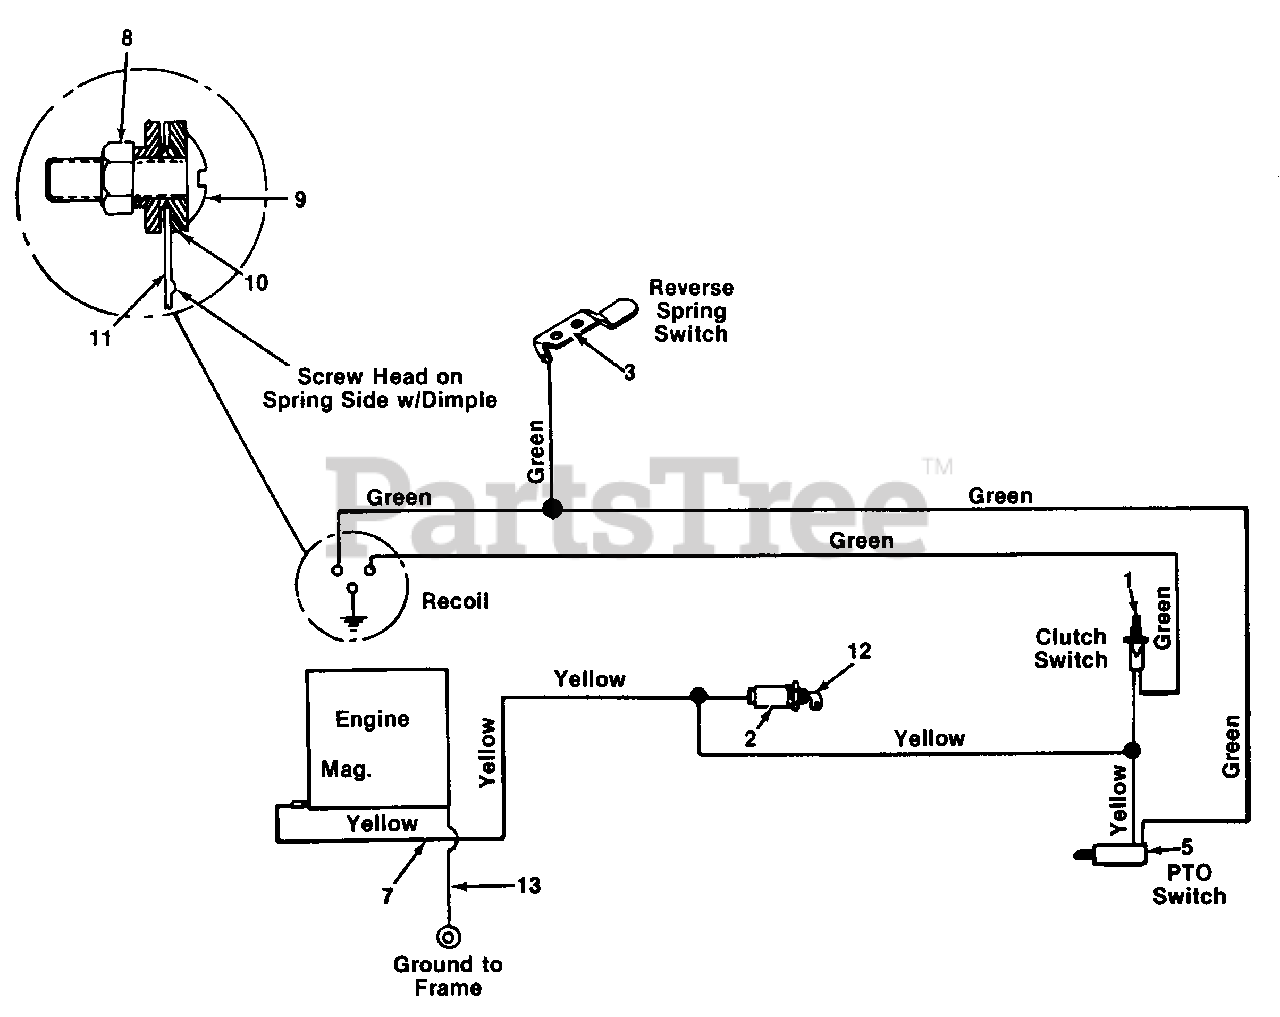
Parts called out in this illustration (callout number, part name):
1	SWITCH-SAFETY
2	SWITCH-KEY TYPE
3	SPRING-SWITCH
5	SWITCH-SAFETY
7	CONDUIT-CONVOLUTED
9	SCREW-TRUSS MACH #10-24 X .62
10	WASHER-FIBER
11	SPRING-SWITCH
12	KEY-IGN (SET OF TWO)
